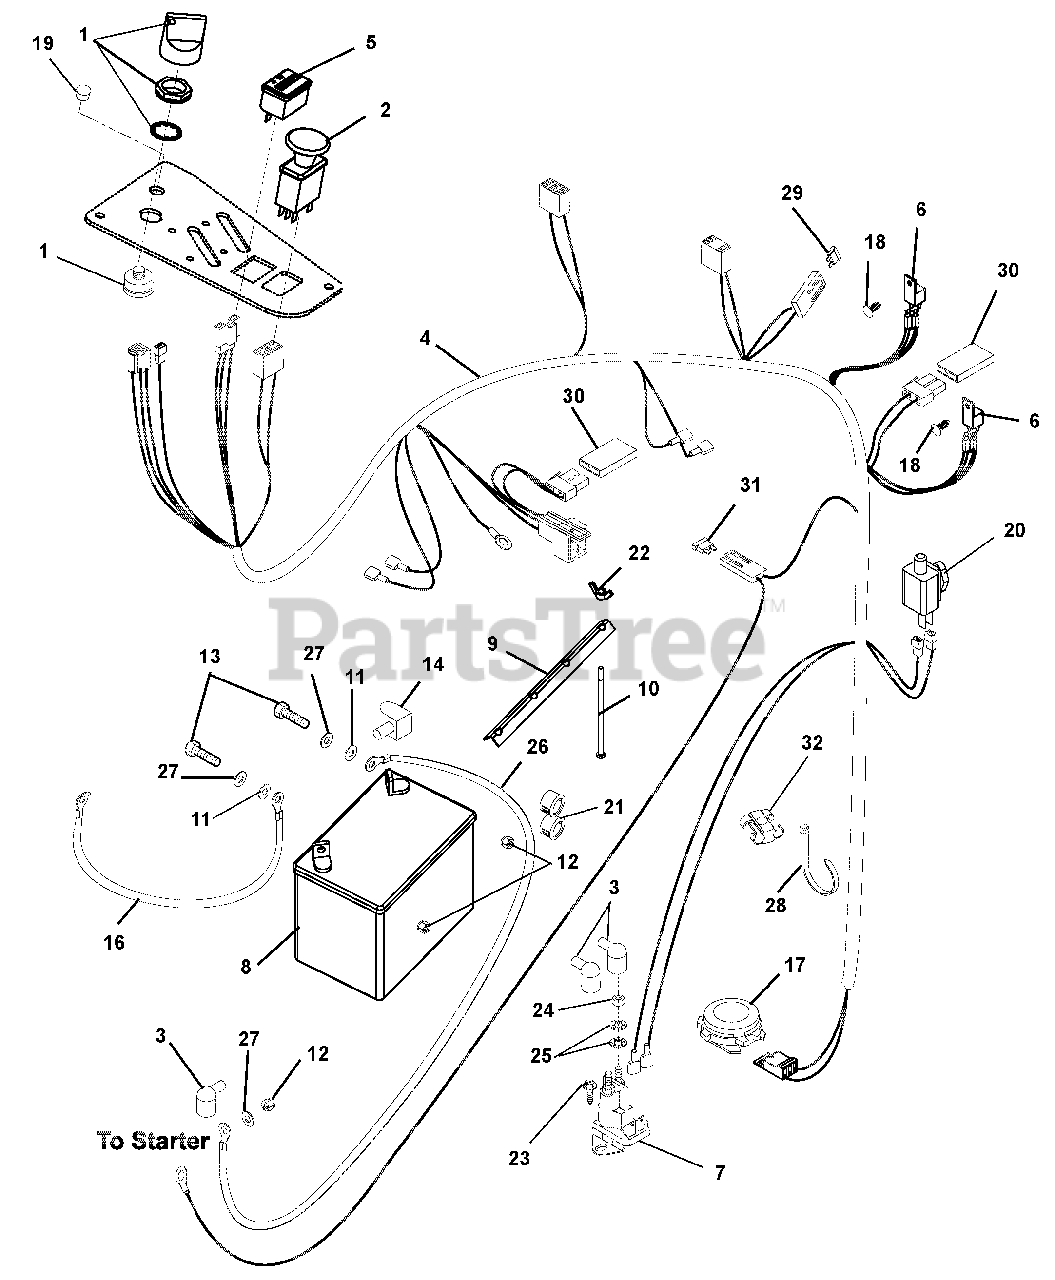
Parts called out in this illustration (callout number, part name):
1	KEY, W/ SHIELD
2	SWITCH, CLUTCH
3	BOOT, BATTERY TERMINAL-RED
4	HARNESS - CZ REMOTE SOL.
5	METER, HOUR W/MAINTENANCE
6	RELAY,SEALED W/DIODE
7	SOLENOID, HP RTV
8	BATTERY, 300 CCA 10U1L
9	HOLD DOWN
10	BLT-RDHDSQNK .25-20X7.50 GR2YZ
11	@WSHR-FL-STL.281X.62X.065 YWZC
12	@NUT-HEX .25-20 YWZC
13	@BLT-HEX .25-20X.75 GR5 YWZC
14	INSULATOR
15	CABLE-POSITIVE BATTERY 9.00"
16	CABLE-NEGATIVE BATTERY 24.00"
17	SWITCH- SEAT
18	RIVET, .25 NYLON PANEL
19	PLUG-HOLE .50 DIA
20	SWITCH, SINGLE POLE N.O.
21	BUSH, PANEL SNAP .687X.875X.56
22	NUT-LK WING .250-20 YWZC
23	@SCR-TAP .25-20X.50 HWH TR YWZ
24	NUT-JAM .31-24 YWZC
25	WSHR-LOCK INT .31 YWZC
26	CABLE, STARTER .31X23.00X.31
27	@WSHR-LK .25X.062 REG YWZC
28	CABLE TIE LG 5-1/2
29	FUSE 20AMP
30	DIODE, CONNECTOR SHELL
31	FUSE-25 AMP ATC TYPE
32	CLIP,T,.31-.38,
